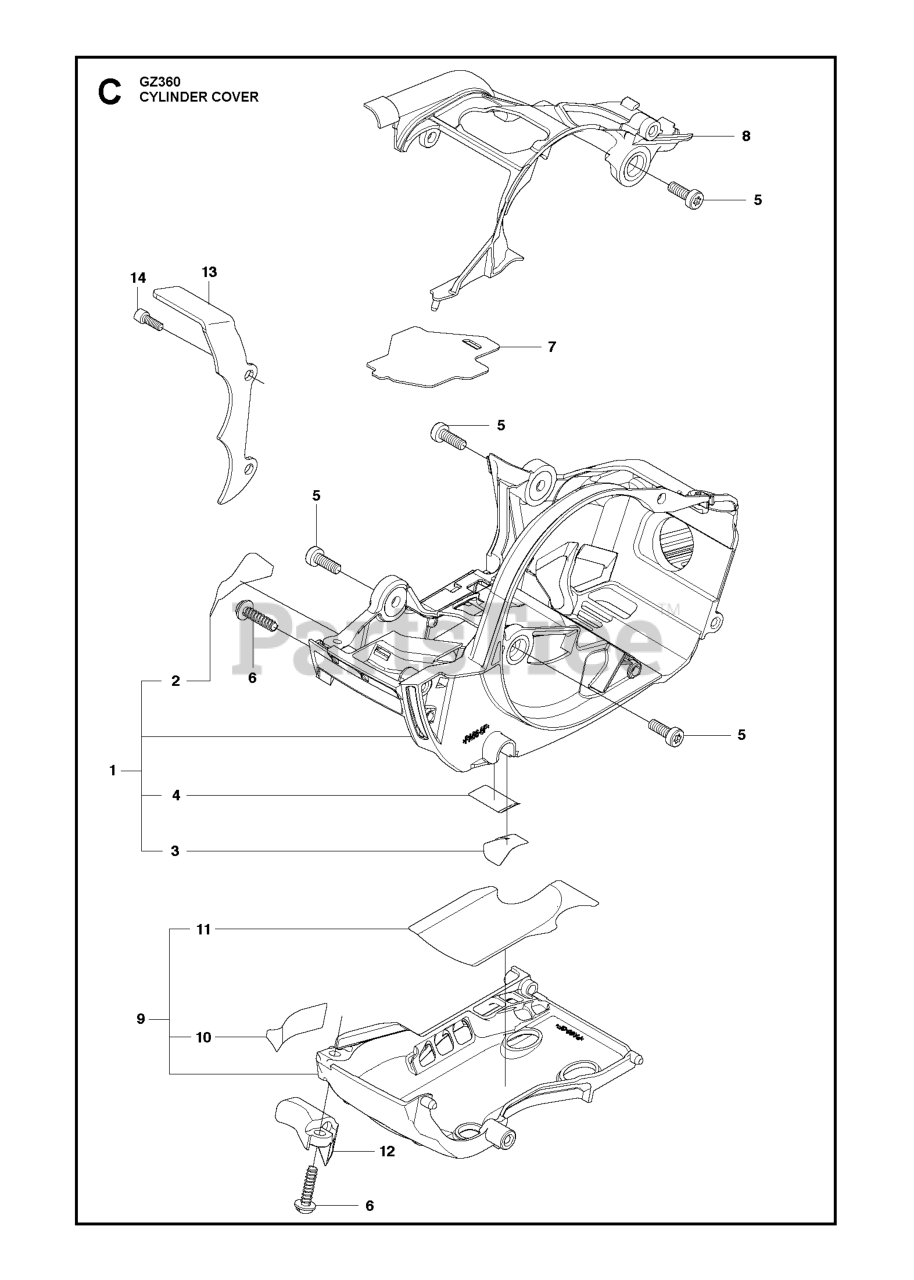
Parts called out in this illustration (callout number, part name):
1	CASE COMP GZ3500L
2	TAPE, CASE
3	TAPE, CASE
4	TAPE, CASE
6	SCREW (RPLS 267132210)
8	COVER TOP GZ3500L
9	CASE ASSEMBLY GZ3500L
12	CATCHER (RPLS -66F1)
13	SPIKE 439
